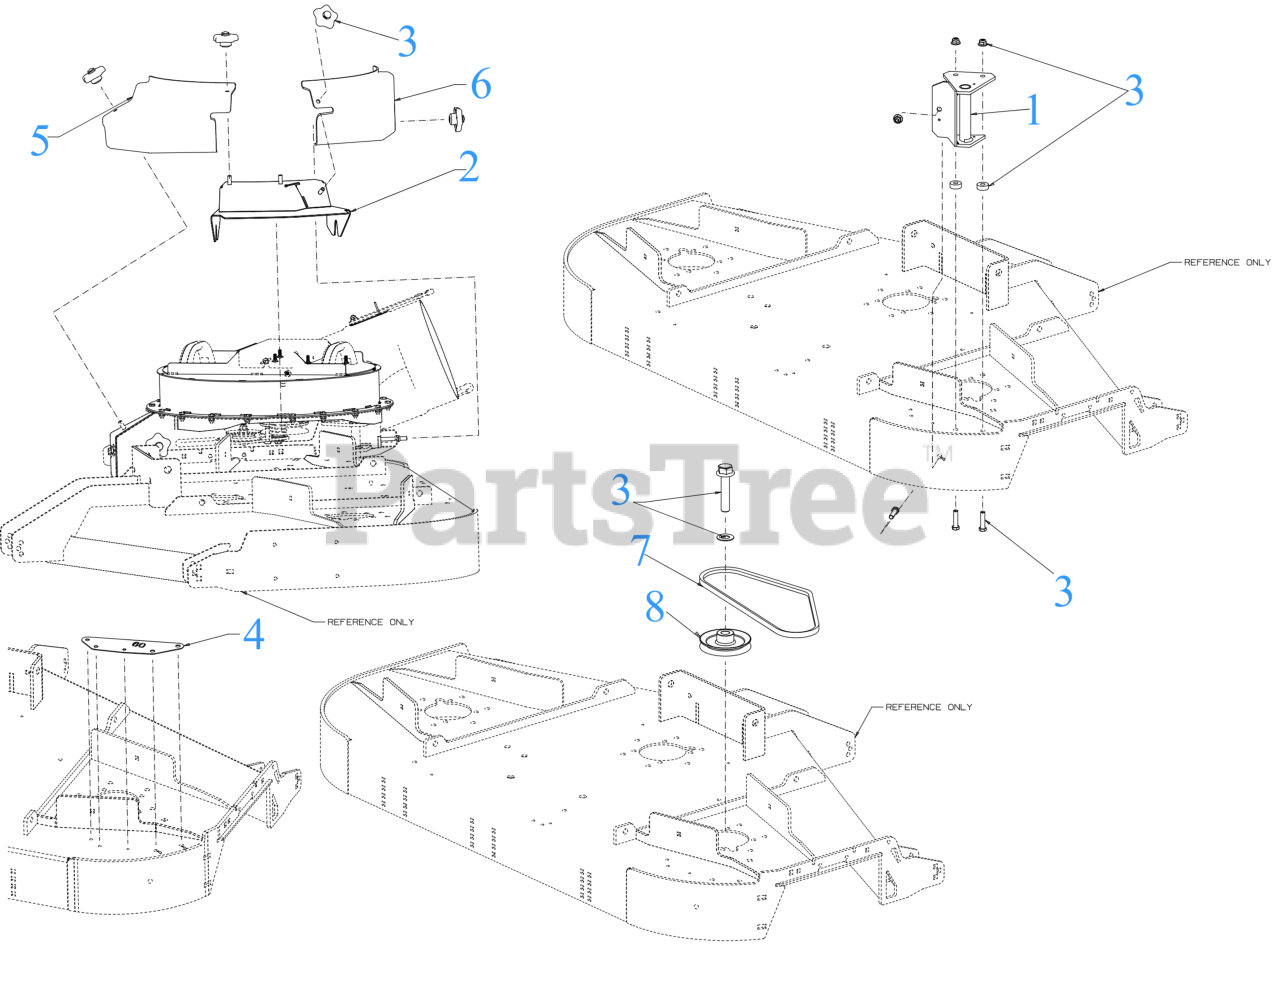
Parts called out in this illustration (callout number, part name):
1	60" BLOWER MOUNT
2	BELT COVER (CENTER)
3	SCREW PACK
4	TEMPLATE PLATE
5	BELT COVER (FRONT)
6	BELT COVER (REAR)
7	DRIVE BELT SEC A X 36.5 COG
